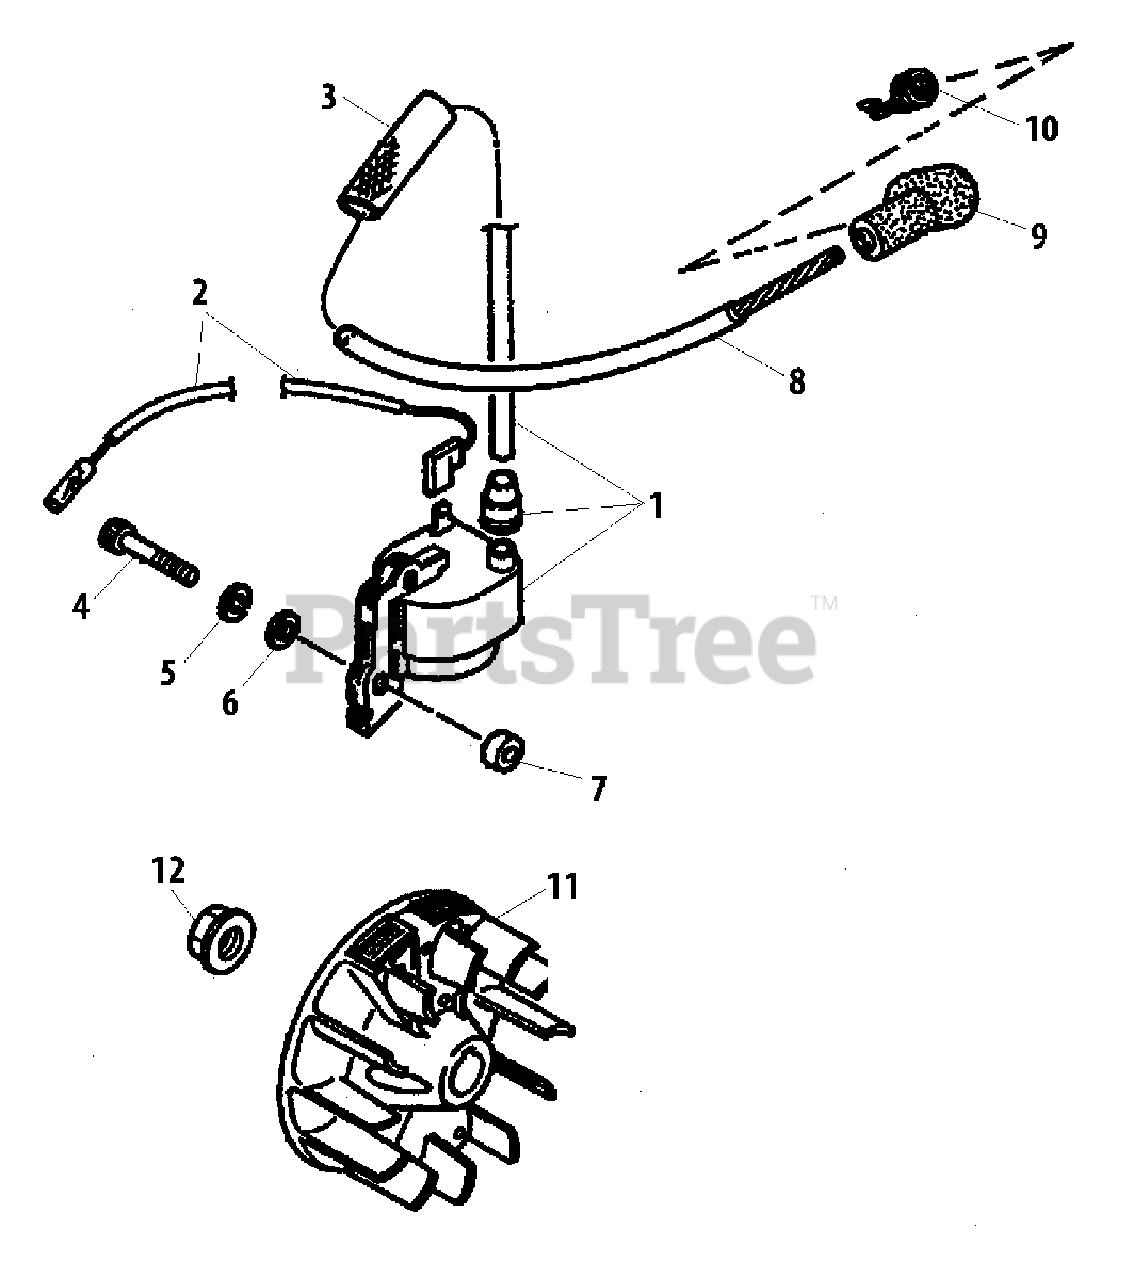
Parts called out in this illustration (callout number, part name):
1	COIL ASSY, IGNITION
2	LEAD - IGNITION
3	TUBE, IGNITION COIL
4	BOLT
5	WASHER, SPRING 4 MM
6	WASHER 4 MM
7	INSULATOR 4.2×11×6
8	TUBE, INSULATOR
9	CAP, SPARK PLUG
10	TERMINAL, SPARK PLUG
11	FLYWHEEL
12	NUT M8
